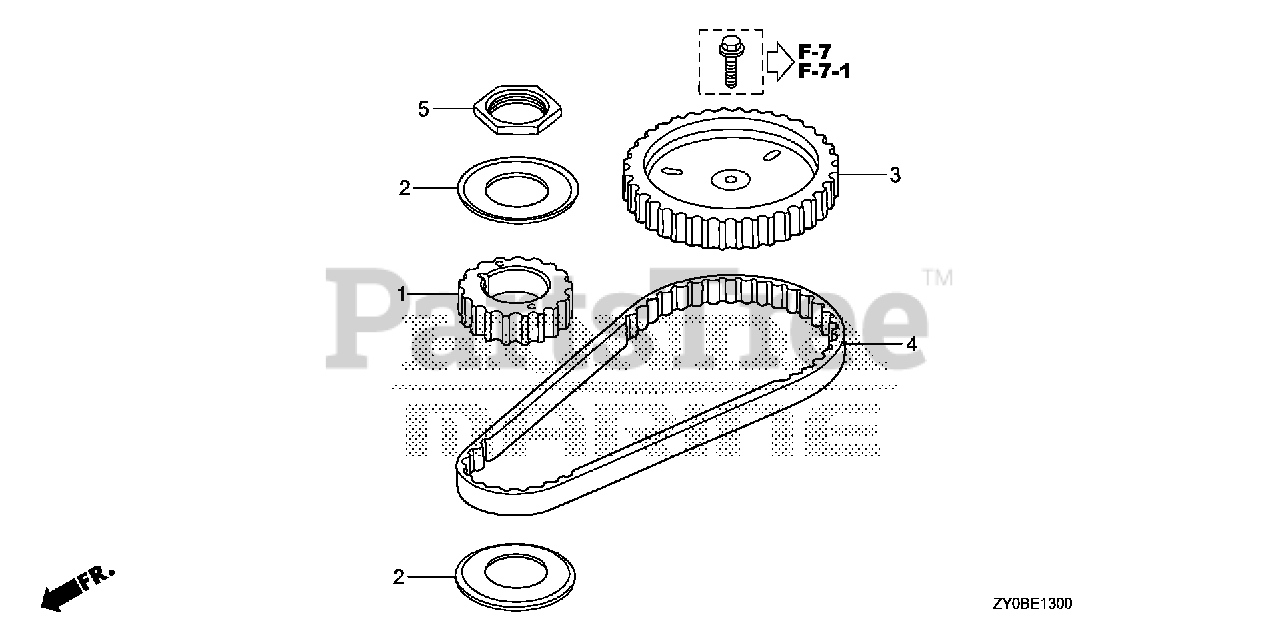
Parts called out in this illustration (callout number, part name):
1	PULLEY, TIMING
2	FLANGE, TIMING PULLEY
3	PULLEY, CAMSHAFT
4	BELT, TIMING (71RU13 B-333)
5	NUT, LOCK (30MM)
